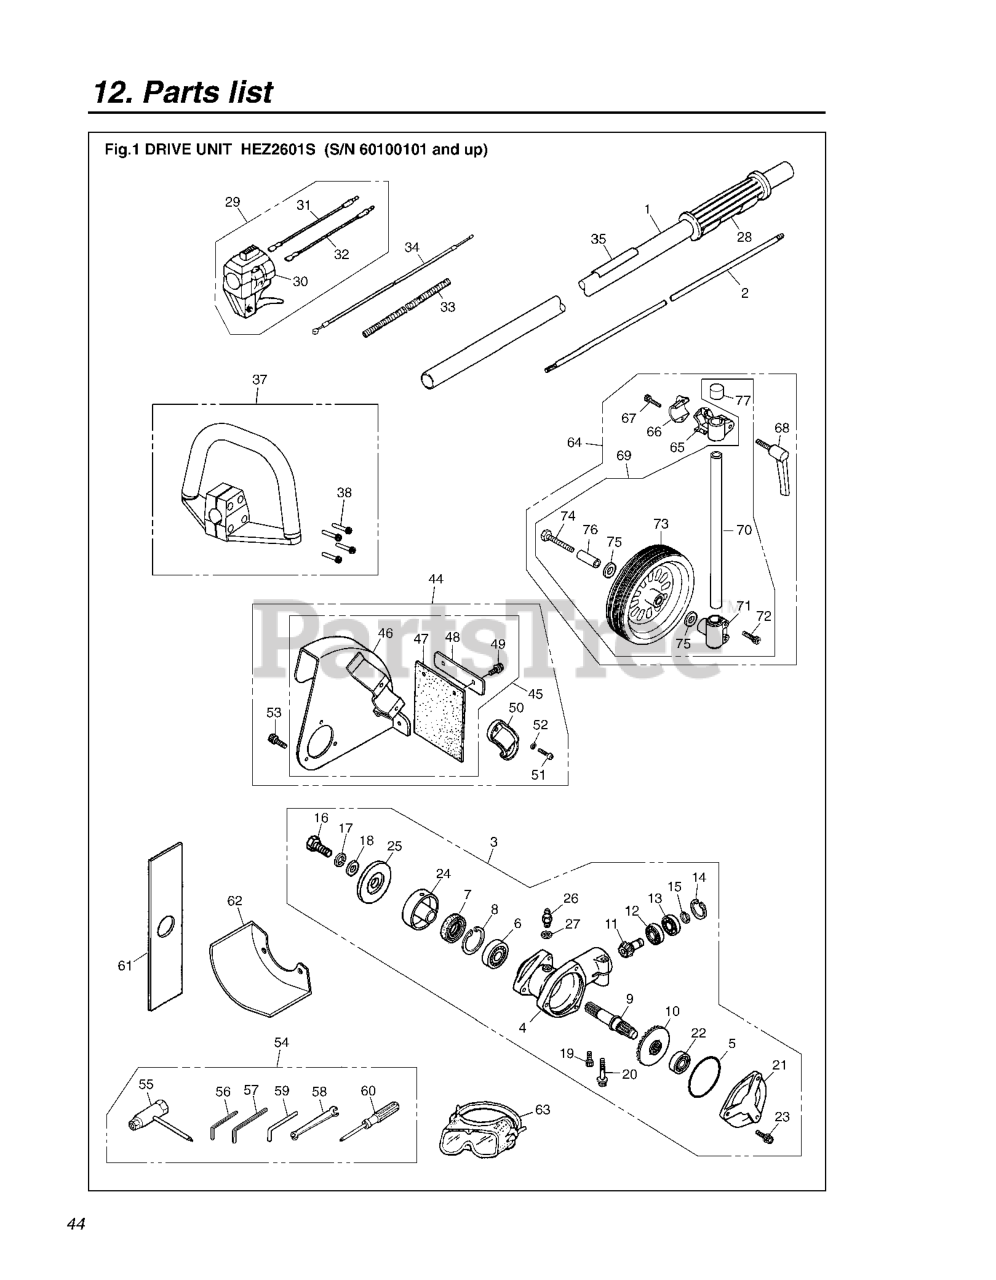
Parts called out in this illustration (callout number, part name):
1	PIPE COMP
3	GEARCASE ASSY
4	GEARCASE
7	OIL SEAL
16	BOLT M8 X L25 L/H
19	BOLT, M5 x 12
23	BOLT M5 X L14 ALLEN
24	HOLDER(A)
25	HOLDER (B)
29	LEVER COMP (RPLS 8488R20343)
30	LEVER (FLEX. LEVER)(RPLS -13)
31	CORD (A), BLACK
32	CORD (B), RED
37	HANDLE ASSY. (RPLS T319514001)
51	BOLT, M6 x 18
53	BOLT M5 X L14 ALLEN
54	TOOL SET
57	Wrench Tool
63	GOGGLExxx (RPLS
64	WHEEL-ASSY***
65	BRACKET-24
67	BOLT, M5 x 22
69	WHEEL ASSY (RPLS -25100)
74	BOLT (RPLS 0101081060)
75	WASHER, M10 x 1.6
76	SPACER, PIPE
